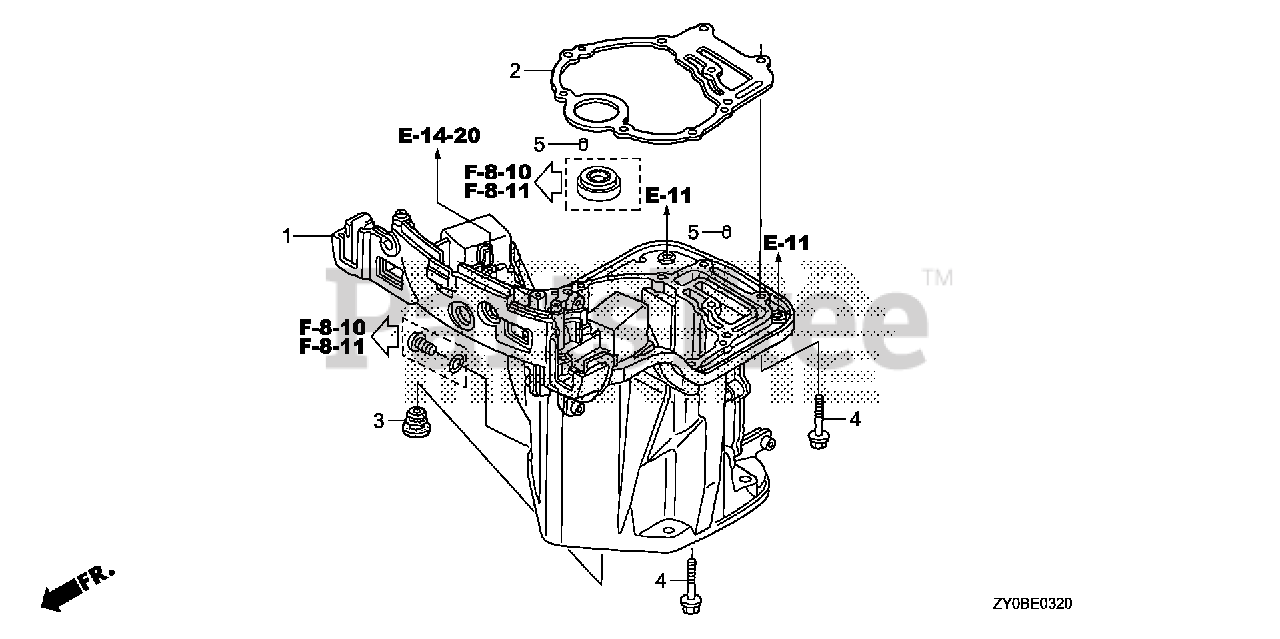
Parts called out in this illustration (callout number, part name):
1	CASE, OIL *NH282MU* (OYSTER SILVER METALLIC-U)
2	GASKET, OIL PAN
3	GROMMET, WATER TUBE
4	BOLT, FLANGE (8X35) Use from Frame SN 4800713.
5	PIN A, DOWEL (6X10)
